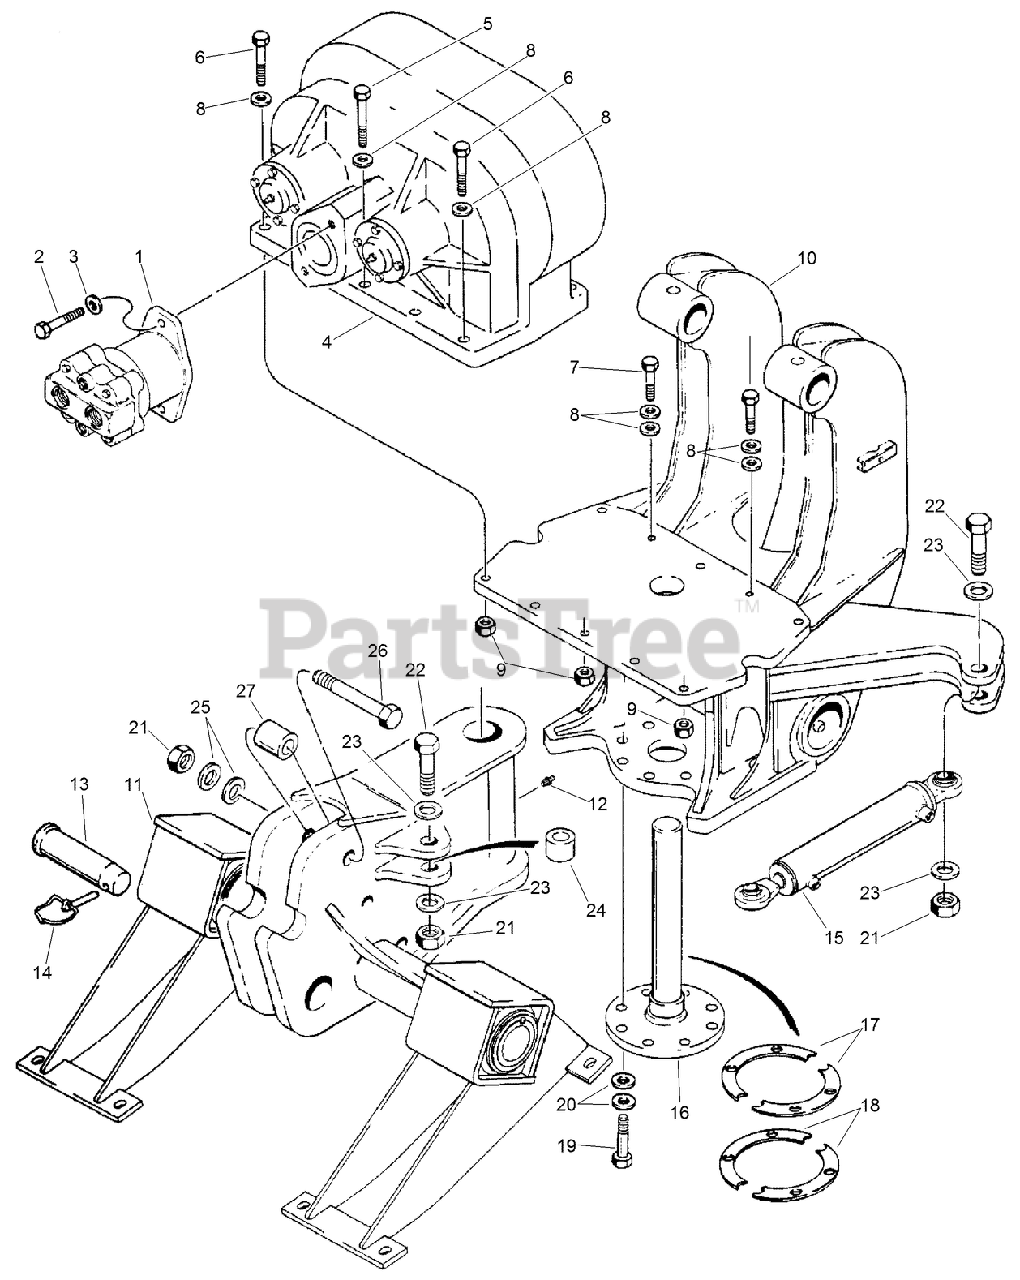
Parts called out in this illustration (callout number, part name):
1	MOTOR ASM-hydrostatic drive, plow
2	BOLT-Hex Hd 1/2 x 1-1/4 GR5 ZND
4	BOX-SHAKER
5	SCREW-HH
6	BOLT-Hex Hd 0.500 x 2.25 GR8 ZND
7	SCREW-HH
9	NUT-HEX
10	FRAME-plow gearbox mounting
11	BRACKET-plow blade mounting
12	FITTING-Lube 1/4-28 Tpr SAE-LT .54 Long
13	PIN-plow blade retaining
14	PIN-KLIK
15	CYLINDER-BLADE
16	AXLE-PIVOT, BLADE MOUNTING
17	SHIM-PLOW PIVOT
18	SHIM-PLOW PIVOT (THICK)
19	SCREW-HH
20	WASHER-FLAT
22	BOLT-HH
24	TUBE-ROD END SPACER
25	WASHER-LOCK
26	BOLT-HH
27	TUBE-SPACER, SOD CUTTER
